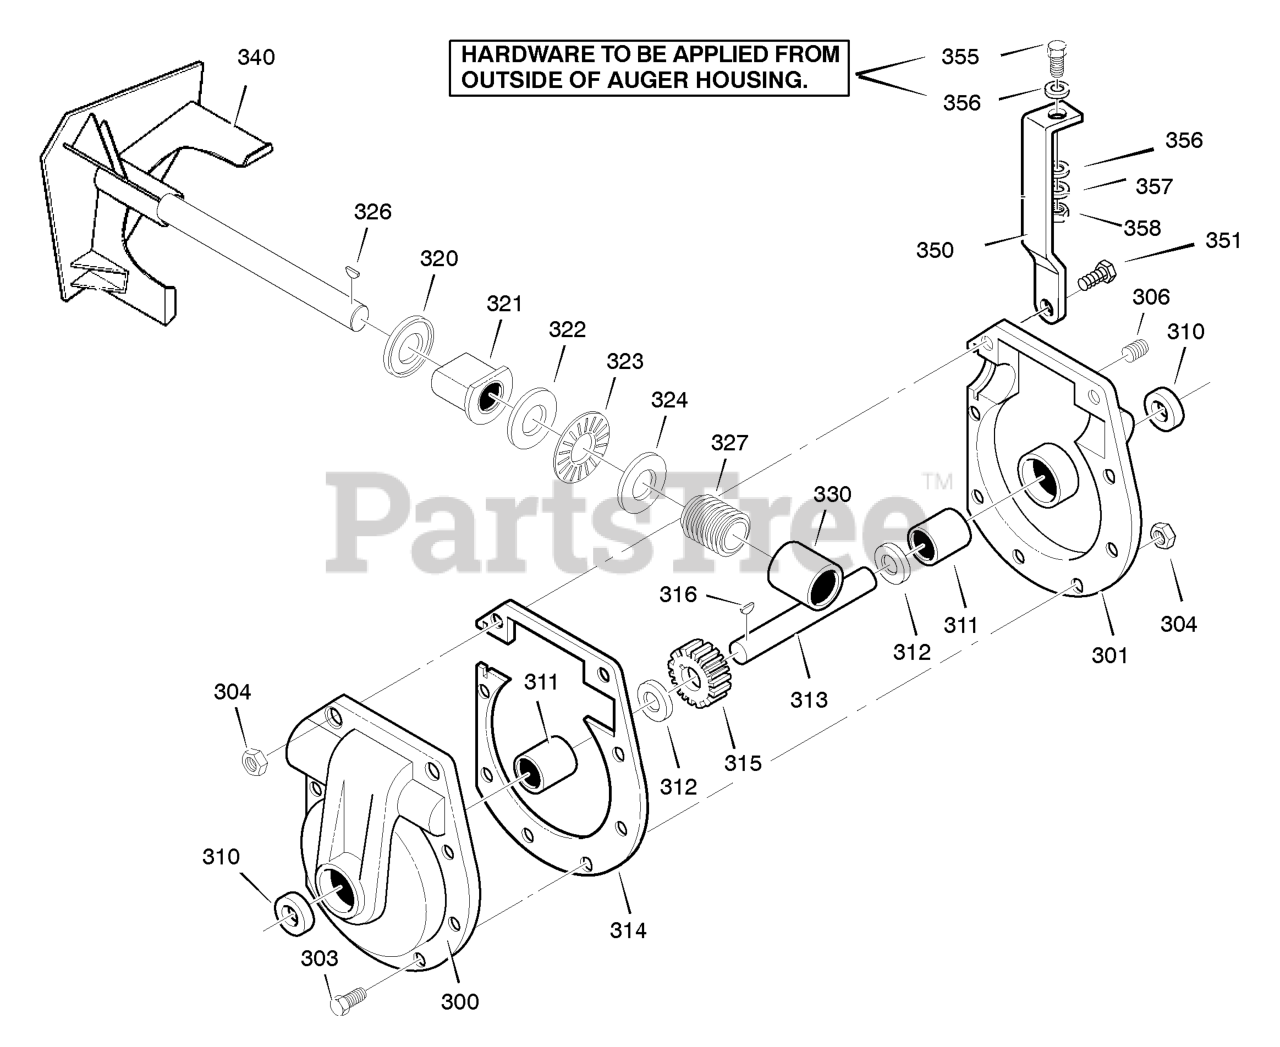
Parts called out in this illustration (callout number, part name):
300	CASE, GEAR, RH
301	CASE, GEAR, LH
303	SCREW, 5/16-24 x 1.00
304	NUT, 5/16-24
306	PLUG, PIPE
310	SEAL, OIL
311	BEARING
312	WASHER, FLAT
313	SHAFT, AUGER OUTPUT
314	GASKET, GEAR BOX
315	WORM GEAR
316	KEY, WOODRUFF #91
320	RING, QUAD
321	BEARING, FLANGE
322	WASHER, FLANGE
323	BEARING, ROLLER
324	WASHER, FLAT
327	GEAR, WORM
330	BEARING
350	BRACE, GEAR BOX
351	SCREW 5/16-24X1.75
355	SCREW, 5/16-18 x 1.25
356	WASHER, FLAT
357	WASHER
358	NUT, 5/16-18 REGHEX
